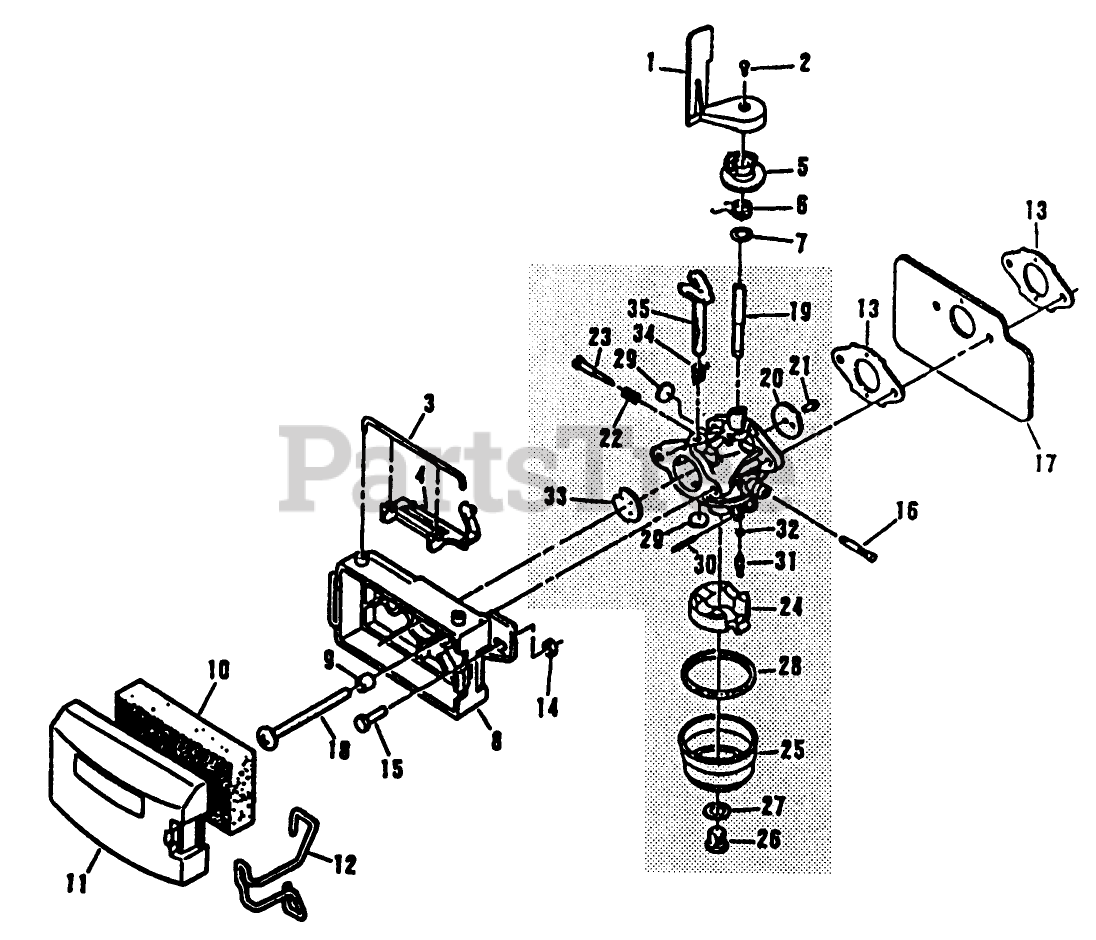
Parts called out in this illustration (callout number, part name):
1	AIR VANE F
2	SCREW F
3	RETAINER
5	COLLAR A/VAVE F
6	THROTTLE SPR E
7	WASHER VF
9	SPACER
12	RETAINER-COVER, FILTER
13	GASKET CARB S
15	SCREW
16	SCREEN FUEL PITTS
17	SHIELD, CARB F
18	SCREW
19	? Throttle Shaft
20	? Throttle Valve
21	? Screw-Throttle Valve
22	? Spring-Idle Needle
23	? Idle Needle
25	? Fuel Bowl
26	? Screw-Bowl Retainer
27	? Bowl Retainer Gasket
28	? Fuel Bowl Gasket
29	? Plug-Welch
30	? Float Shaft
31	? Inlet Needle Valve
32	? Valve Seat
33	? Choke Valve
34	? Choke Return Spring
35	? Choke Shaft
